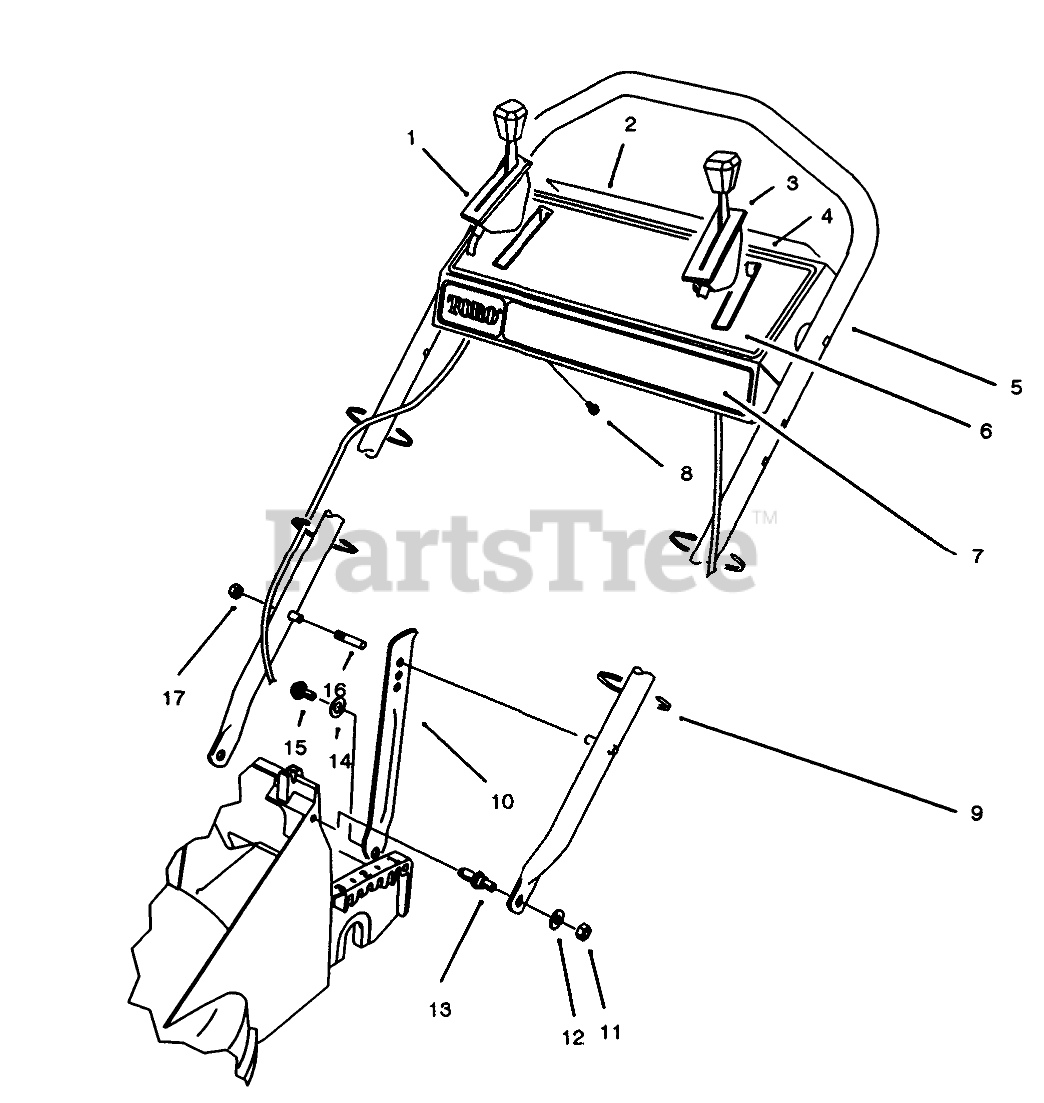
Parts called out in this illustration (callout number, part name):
1	Control-Ground Speed
2	DECAL - PANEL, REAR
3	THROTTLE CONTROL
4	Panel-Control (Incl. Ref. #2 & 6)
5	HANDLE
6	DECAL - INSTRUCTION
7	DECAL - TORO PANEL
8	SCREW-HWHTF
9	TIE-CABLE
10	HANDLE LATCH
11	NUT-LOCK, NI
12	WASHER-PLAIN
13	SCREW - SHOULDER STUD
14	NYLON WASHER
15	SCREW-SHOULDER
16	HANDLE PIN
17	NUT-LOCK, NI
